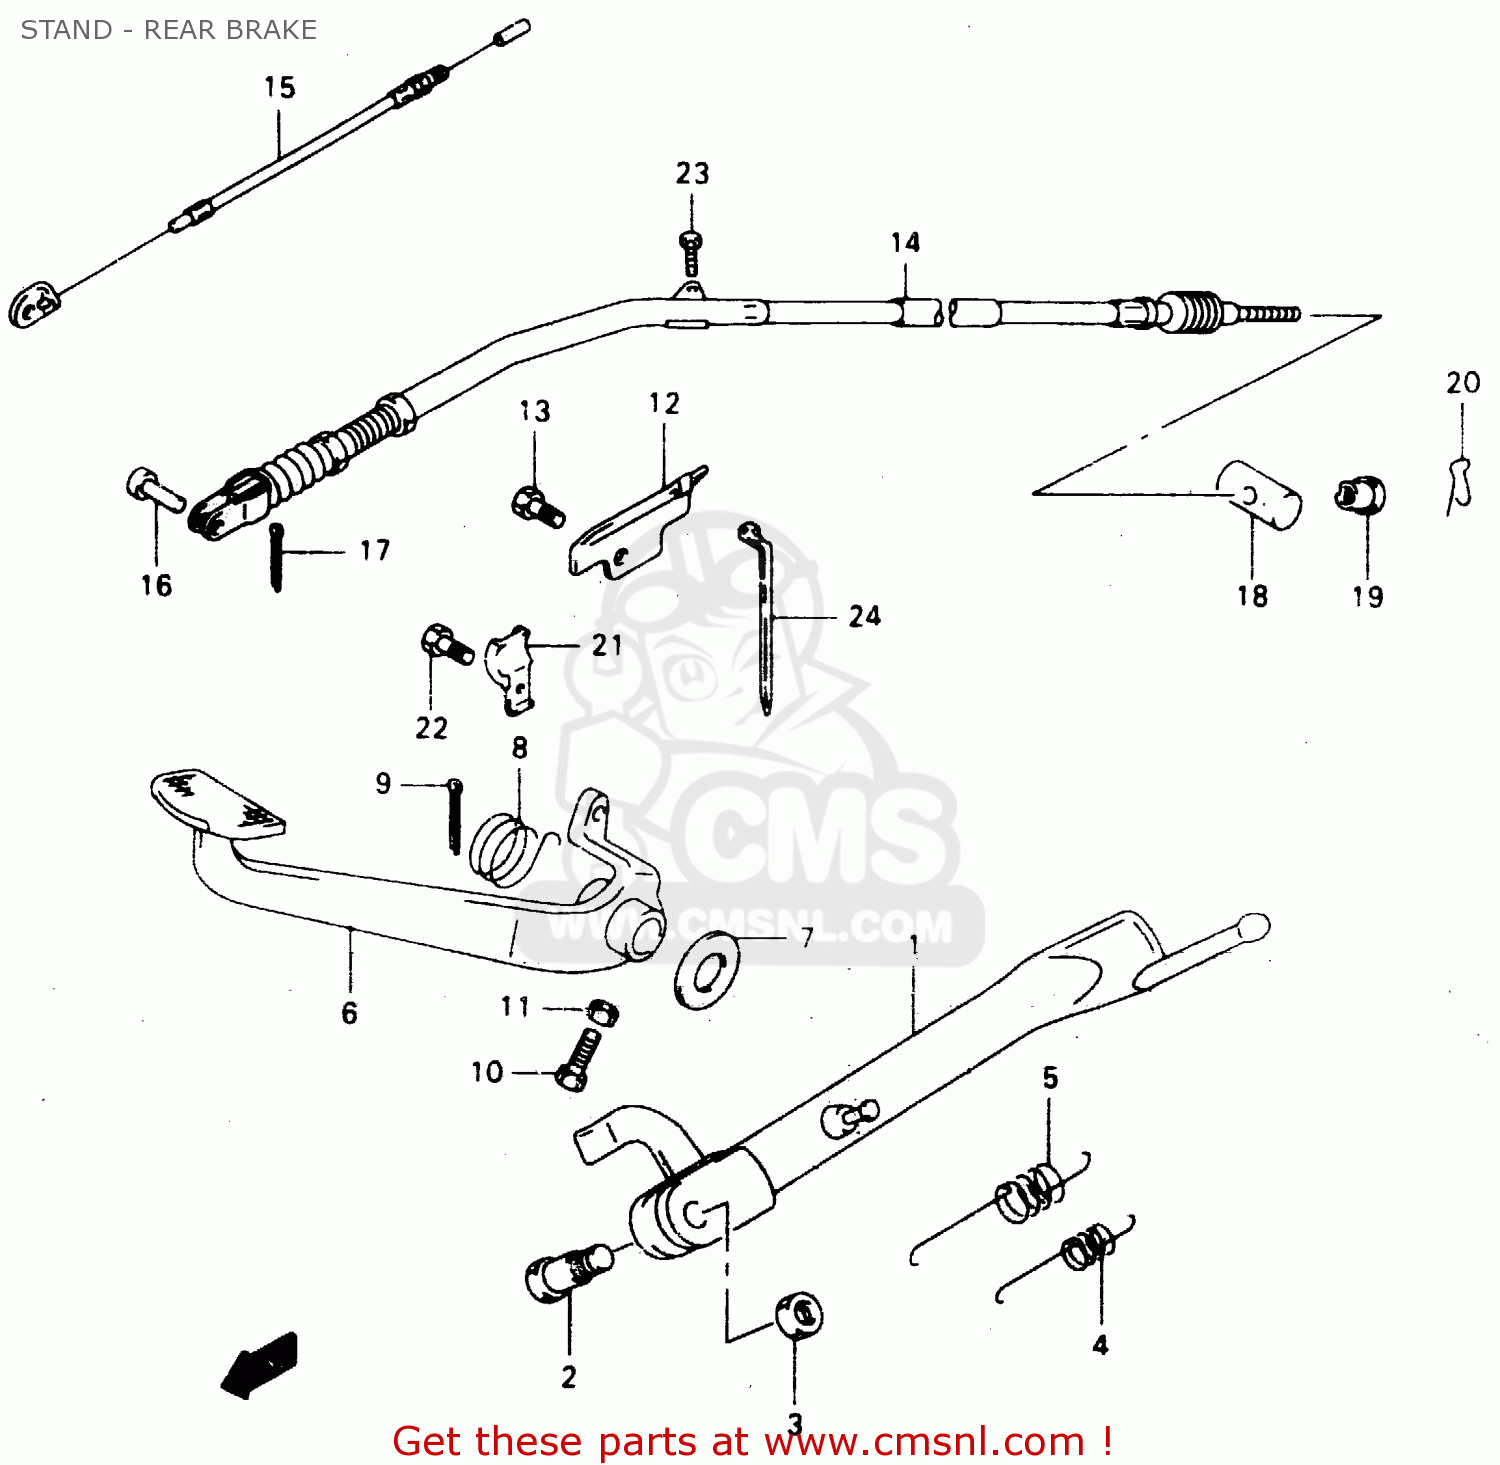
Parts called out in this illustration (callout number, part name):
1	STAND,PROP
2	BOLT(10X34)
3	NUT
4	SPRING
5	SPRING
6	PEDAL,BRAKE
7	WASHER(16.5X22X1)
8	SPRING
9	COTTER PIN
10	BOLT
11	NUT
12	GUARD,BRAKE CABLE
13	BOLT
14	CABLE COMP,REA
15	CABLE,STOP LAMP SWITCH
16	PIN(L:17.5)
17	PIN
18	PIN(13X18)
19	NUT
20	CLIP
21	GUIDE,RR BRAKE CABLE
22	BOLT
23	BOLT,OIL FILLE
24	CLAMP(L:145)
